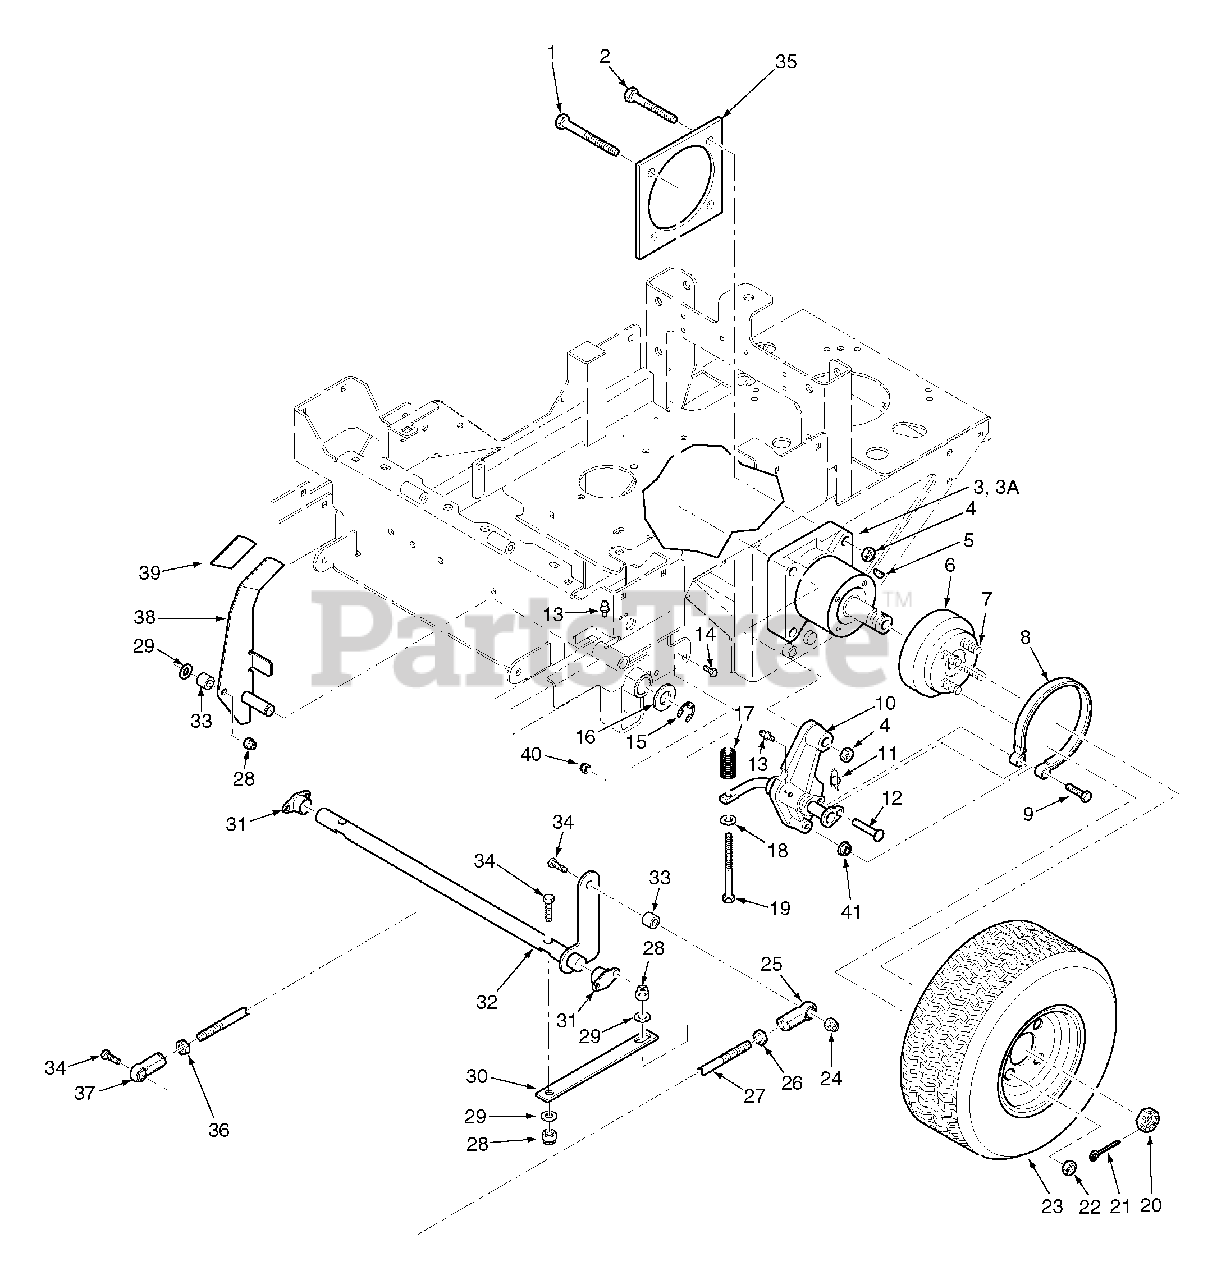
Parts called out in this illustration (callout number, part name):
1	Bolt, Hex Head 1/2-13 x 3-3/4"
2	Bolt, Hex Head 1/2-13 x 2-1/2"
3	Wheel Motor, L.H. - Hydro-Gear
3A	Wheel Motor, R.H. - Hydro-Gear
4	Nut, 1/2-13 Center Lock
5	Key, Woodruff 5/16 x 1"
6	Wheel Hub Assembly
7	Bolt, Serr. Flange 1/2-20 x 1.563"
8	Brake Band Assembly
9	Bolt, Hex Head 3/8-16 x 2-1/2"
10	Brake Linkage Weldment, L.H. SZC
11	Pin, Rue Cotter 3/8 Dia.
12	Clevis Pin, 3/8 x 1.93"
13	Grease Fitting, 1/4-28
14	Bolt, Hex Head 5/16-18 x 3/4"
15	Retaining Ring, .625 Ext.
16	Flatwasher, 5/8-.688 x 1.75 x .134
17	Spring, Brake
18	Flatwasher, 3/8-.391 x .938 x .105 HD
19	Bolt, Hex Head 3/8-16 x 3-1/2"
20	Nut, Hex Castle 1.0-20 UNEF
21	Cotter Pin, 9/64 x 1-1/2"
22	Lug Nut, 1/2-20
23	Wheel Assembly, 23 x 8.5-12 4 Ply (36")
24	Nut, Elastic Stop 3/8-16
25	Rod End, 3/8-24 R.H. Female
26	Nut, 3/8-24 UNF Jam
27	Link, Brake 3/8-24 x 8-5/8"
28	Nut, Elastic Stop 3/8-16
29	Flatwasher 3/8-.391 x .938 x .105 HD
30	Spring, Flat Brake
31	Bushing, Self Align
32	Brake Shaft Weldment, SZC
33	Spacer
34	Bolt, Hex Head 3/8-16 x 1-3/4"
35	Plate Weldment, Motor Backing
36	Nut, 3/8-24 UNF L.H. Jam
37	Rod End, 3/8-24 L.H. Female
38	Brake Lever
39	Grip, Brake Lever
40	Nut, Elastic Stop 5/16-18
41	Nut, Serr. Flange 3/8-16
